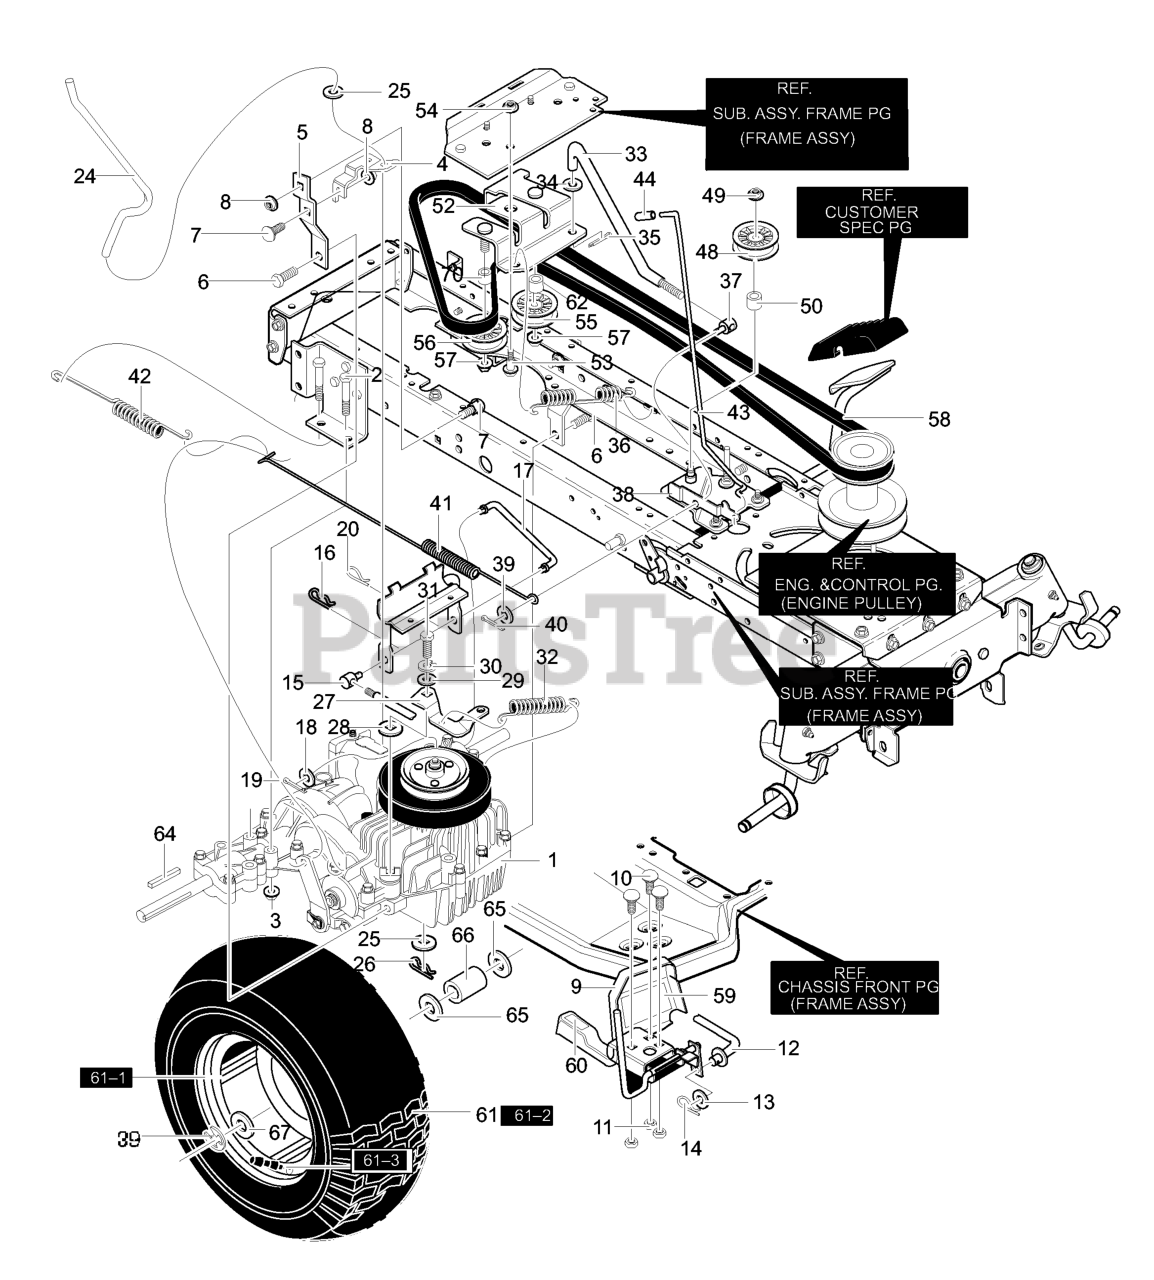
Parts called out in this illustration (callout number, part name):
1	Transaxle, VST205 **
2	Screw, 5/16-18 x 2.50
3	Nut, 5/16-18 Wdfllk
4	Bracket, Disconnect
5	Torque Strap
6	Screw, 5/16-18 x 0.75
7	Bolt, 5/16-18x.63
8	Nut, 5/16-18 Hexwdfllk Wh
9	Pedal Assy., Hydro
10	Bolt, 5/16-18x.75
11	Nut, 5/16-18
12	Rod, Pedal Link
13	Washer
14	Hair Pin
15	Adjust Nut 1/2-13
16	Hair Pin
17	Rod Hydro Link
18	Flat washer
19	Cotter Pin
20	Hair Pin
24	Rod, Disconnect
25	Washer, Flat
26	Pin, Cotter
27	Arm Disconnect
29	Flat washer
30	Washer
31	Screw, 1/4-28x.75
32	Spring, Extension
33	Rod, Clutch
34	Flat washer
35	Cotter Pin
36	Spring, Clutch
37	Nut, Adjusting
38	Latch, Park Brake
39	Flat washer
40	Cotter Pin
41	Spring, Extension
42	Spring, Tension
43	Park Brake Rod
44	Grip
48	Pulley, Idler
49	Nut, 3/8-16
50	Spacer, 1/2 to 17MM
52	Asm., Bracket Idler
53	Bolt, 3/8-16
54	Nut, 3/8-16
55	Pulley, Idler
56	Pulley, Idler
57	Nut, 3/8-16
58	Belt, Motion Drive
60	Pad, Toe Sandpaper
61	Tire & Rim
61-1	Valve Stem
62	Spacer 1/2 to 17MM
64	Key, Square
65	Flat washer
66	Spacer .87x1.78
67	Flat washer
68	Ring, E
70	Spacer 1/2 to 17MM
